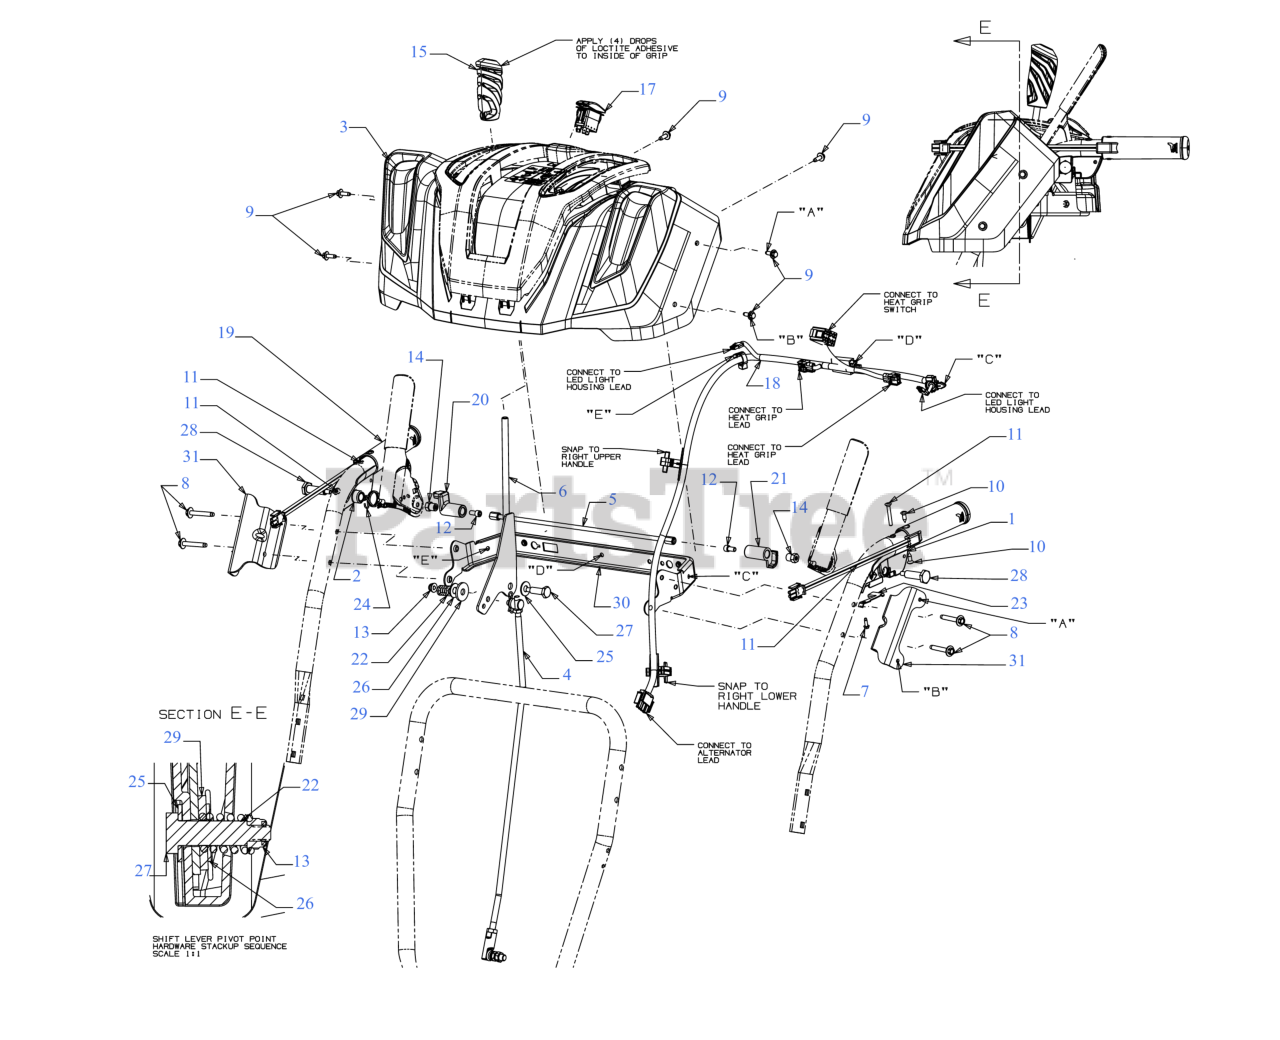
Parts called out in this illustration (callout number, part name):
1	CLUTCH LOCK HANDLE ASSEMBLY (LH)
2	CLUTCH LOCK HANDLE ASSEMBLY (RH)
4	SHIFT ROD ASSEMBLY
6	SHIFT LEVER (POWDER BLACK)
7	SCREW #8-16 x .50
8	SCREW 1/4-20 x 1.625
9	SCREW M6-1 x .625
10	SCREW-AB #12-24 x .625
11	SCREW #10-24 x 1.375
12	SCREW 1/4-20 x .50
13	FLANGE LOCK NUT
14	HEX NUT W/PATCH
15	PTO HANDLE GRIP .355 ID
17	HEATED GRIP SWITCH
18	HARNESS (TWO HEADLIGHT)
19	HEATED GRIP
21	CLUTCH LOCK CAM
22	COMPRESSION SPRING
23	CLUTCH SPRING
24	TORSION SPRING
25	FLAT WASHER .40X.88X.060
26	FLAT WASHER
27	SHOULDER SCREW
28	SHOULDER SCREW .437 x 1.345 1/4-20
29	FRICTION WASHER
30	HANDLE SUPPORT BRACKET (POWDER BLACK)
31	HANDLE PANEL BRACKET (POWDER BLACK)
